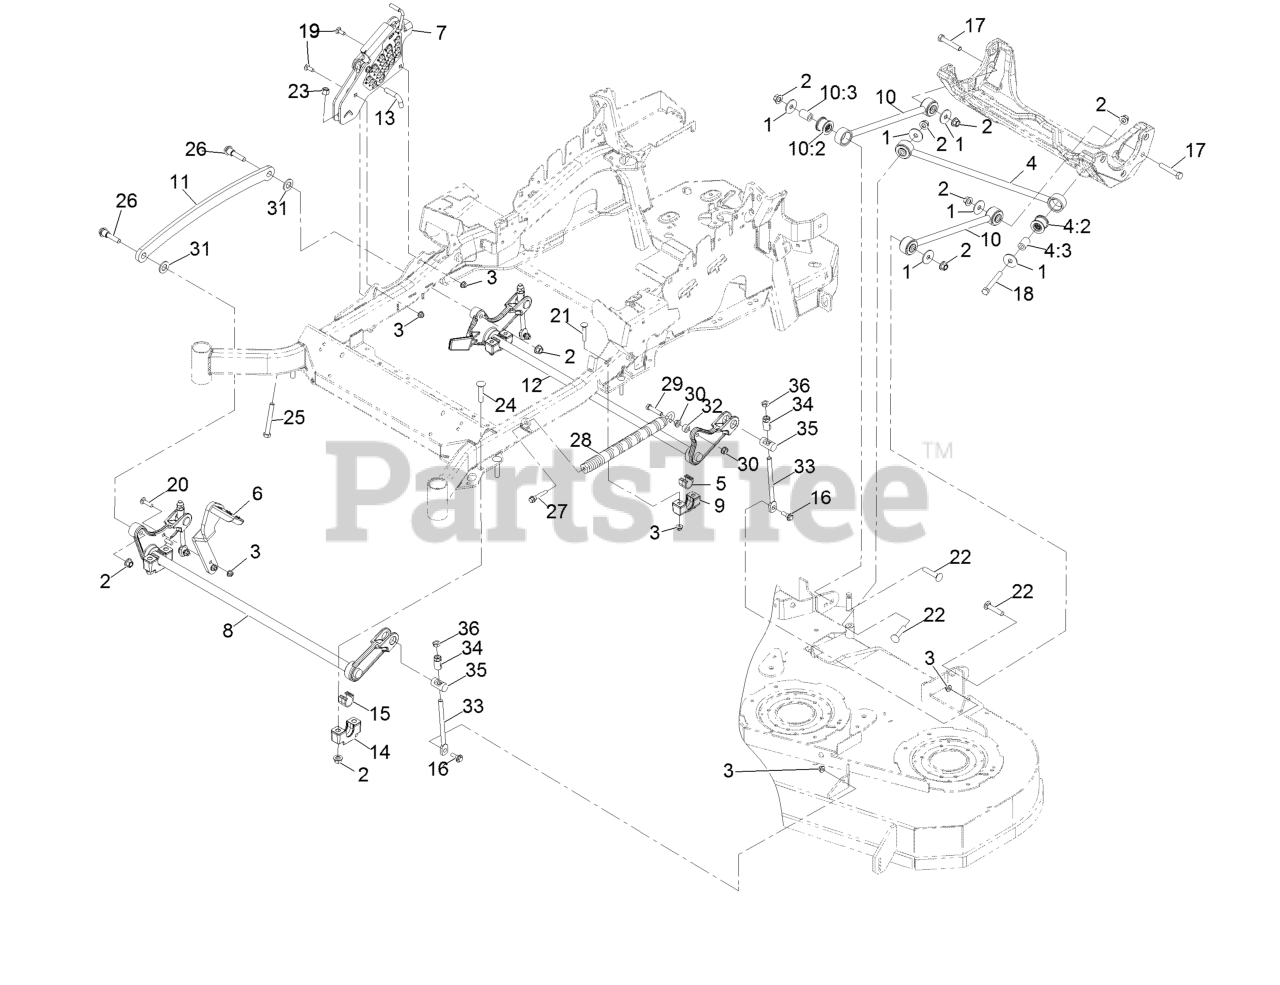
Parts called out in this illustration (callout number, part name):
2	Nut-Lock 1/2-13
3	Nut-Nyloc 3/8-16 Flg
4	Panhard Rod ASM
4:2	Bushing-Suspension, Rubber
5	Bearing-Cross Shaft, Rear
6	Lever-Foot
7	HOC ASM
8	Decklift-Front
9	Support-Cross Shaft, Bearing Rear
10	Deck Strut ASM
10:2	Bushing-Suspension, Rubber
11	Link-Lift, Deck
12	Lift-Deck, Rear
13	Pin-HOC
14	Support-Cross Shaft, Bearing
15	Bearing-Cross Shaft, Front
16	Screw-Hex Flange 3/8-16 X.80
17	Screw-HH 1/2-13 X 3
18	Screw-HH 1/2-13 X 4
19	Bolt-Carriage 3/8-16 X 1
20	Bolt-Carriage 3/8-16 X 1 1/2
21	Bolt-Carriage 3/8-16 X 2 1/4
22	Bolt-Carriage 1/2-13 X 2 1/2
23	Nut-Nyloc 1/2-13
24	Bolt-Carriage 1/2-13 X 2 1/2 Spl Neck
25	Bolt-HH 1/2-13 X 4 Tap
26	Screw-Hex Flange 1/2-13 X 1.90
27	Screw-Shcs 3/8-16 X 2.212
28	Spring-Extension
29	Screw-HH 7/16-14 X 2
30	Nut-Whizlock 7/16-14
31	Washer-3/4 SAE
33	Link-Adjuster, Deck Lift
34	Adjuster-Lift, Deck
35	Trunnion
36	Nut-Jam 1/2-13
